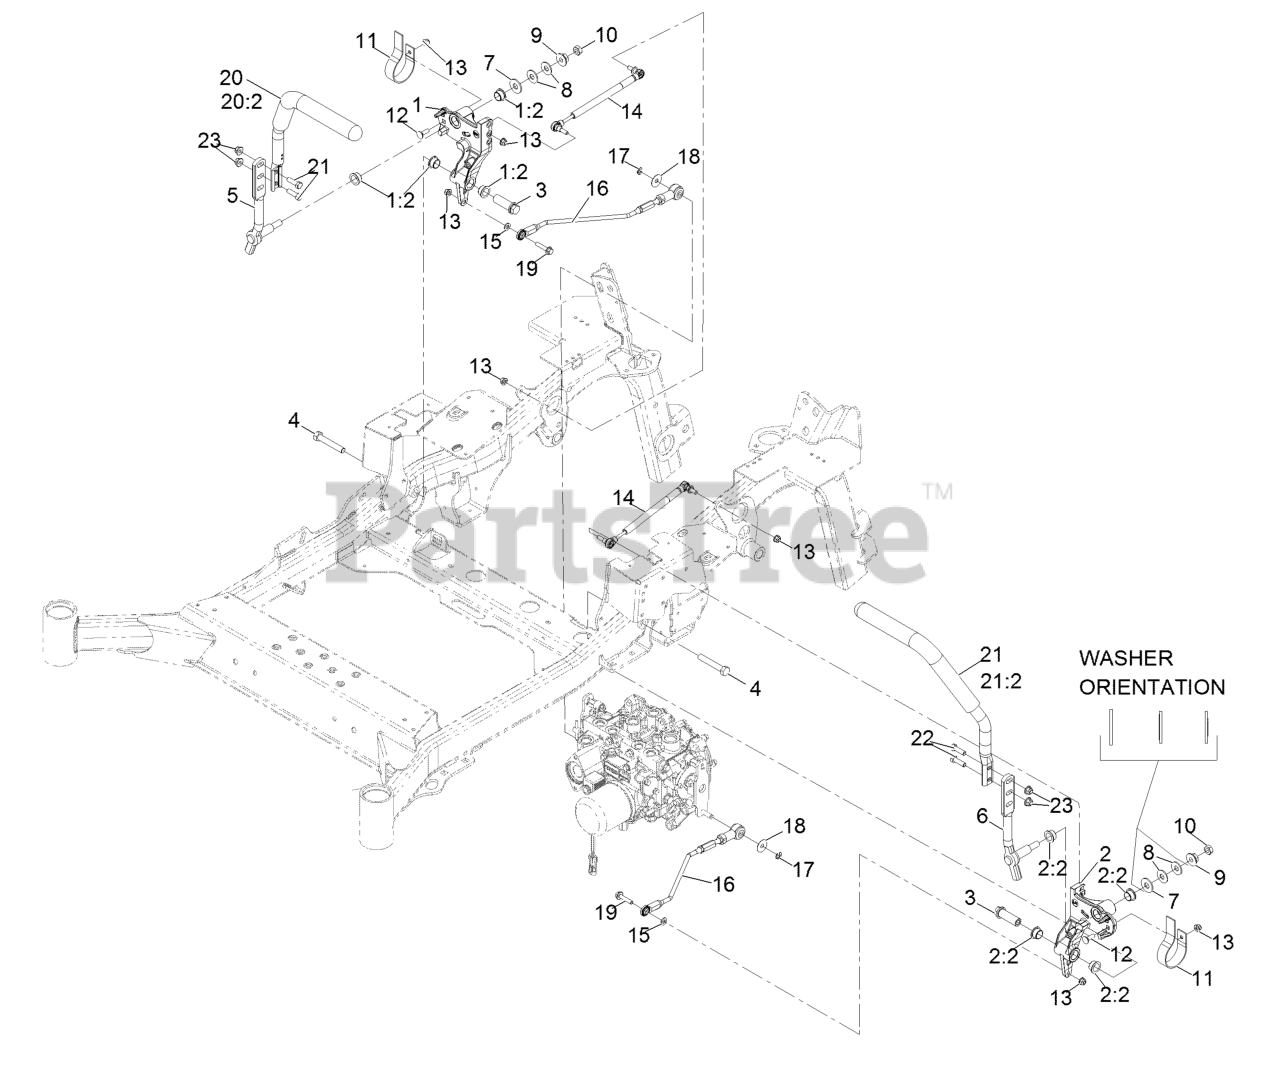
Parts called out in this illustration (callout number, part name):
1	RH Motion Control And Bushing ASM
1:2	Bushing-Flanged
2	LH Motion Control And Bushing ASM
2:2	Bushing-Flanged
3	Hub-Threaded
4	Screw-HH 1/2-13 X 3
5	Lever-Control Motion, RH
6	Lever-Control Motion, LH
7	Washer
8	Washer, Spring Disc 1/2
9	Nut-Hex 1/2-13 Flange
10	Nut-Jam 1/2-13
11	Spring-Leaf
12	Bolt-Carriage 5/16-18 X 1
13	Nut-Nyloc 5/16-18 Flg
14	Damper-Control, Motion
15	Washer-5/16 SAE
16	Front Linkage Rod ASM
17	Ring-Retaining
18	Washer-Plain
19	Screw-Hex Flange 5/16-18 X 1 1/2
20	RH Steering Handle ASM
20:2	Grip-Control, Lever
21	LH Steering Handle ASM
21:2	Grip-Control, Lever
22	Screw-HH 3/8-16 X 1 1/4
23	Nut-Nyloc 3/8-16 Flg
